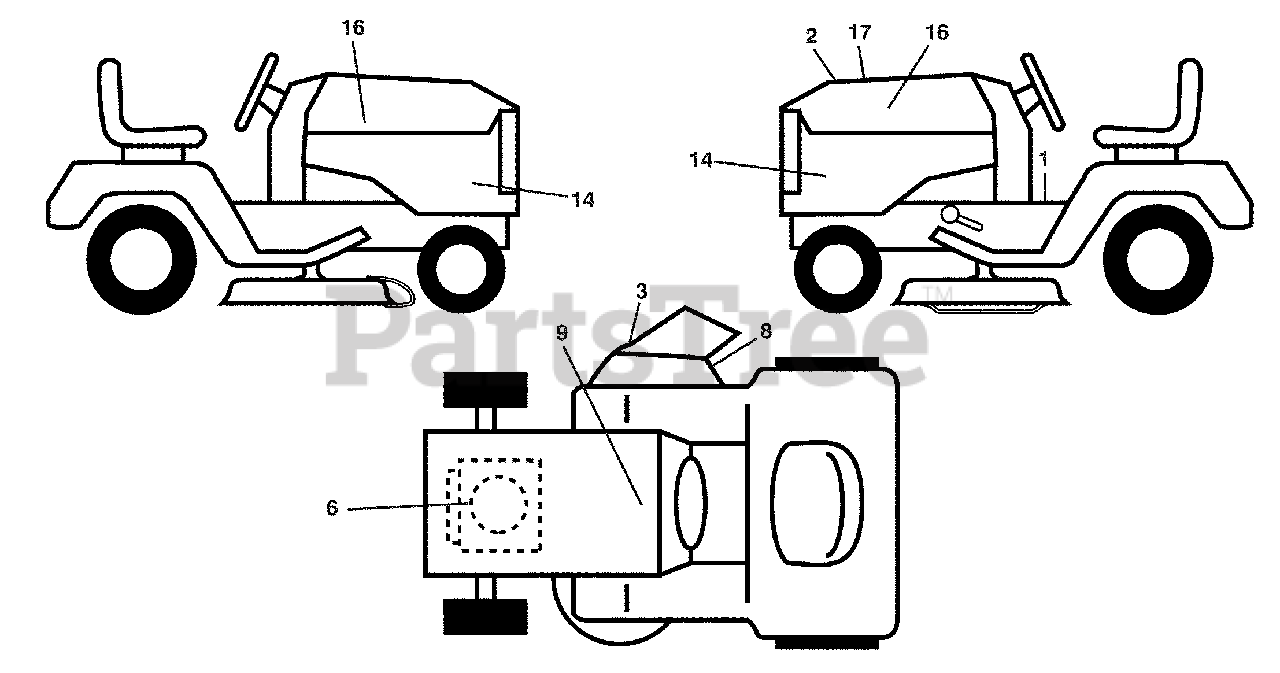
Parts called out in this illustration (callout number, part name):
1	Decal, Operator's
2	Decal, Warning E85
3	Decal, Warning
6	Decal, Eng. HP
8	Decal, Mower Sch.
9	Decal, Battery Dnge/Poi
14	Decal, Panel Side
16	Decal, Hood Logo
17	Decal, Replacement
